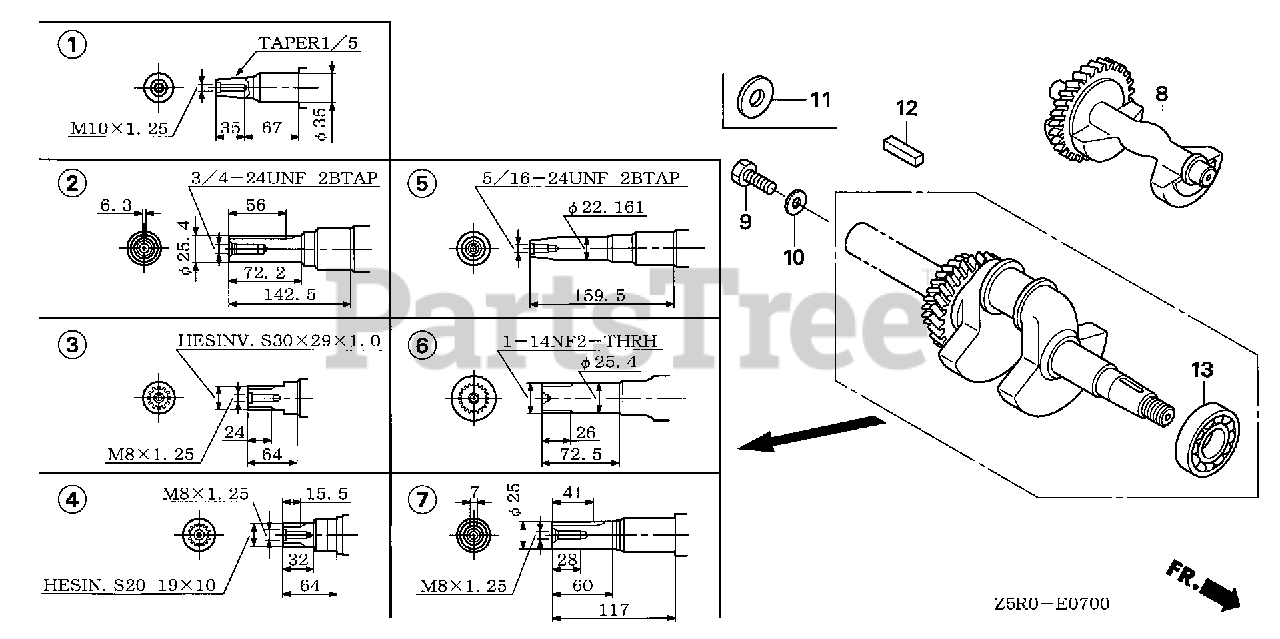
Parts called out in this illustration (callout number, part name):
7	CRANKSHAFT
8	WEIGHT, BALANCER
9	BOLT, HEX. (8X25)
11	WASHER, LOCK (8.5X35X4.5)
12	KEY (7X7X33) (OVER SIZE) (YELLOW)
13	BEARING, RADIAL BALL (6207SH)
